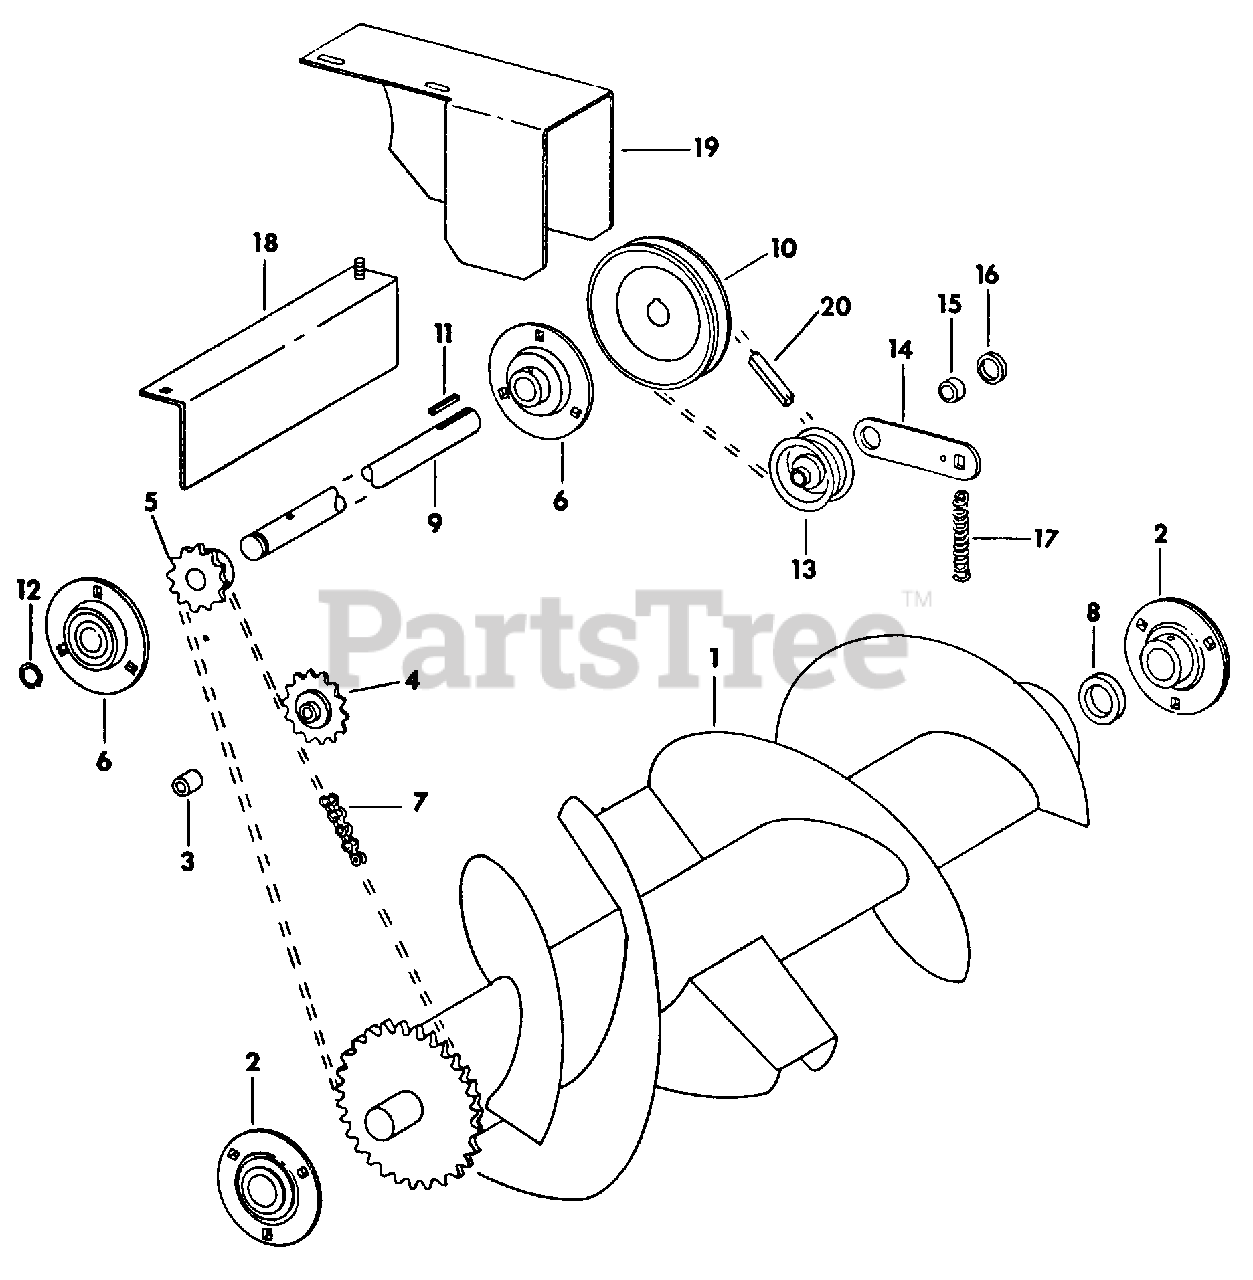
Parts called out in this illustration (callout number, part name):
1	Rotor Assy, Welded
2	Bearing w/o Locking Collar
3	Spacer, Chain Idler Mounting
4	Idler, Chain
6	Bearing w/Set Screw
7	Chain, Roller
8	Spacer, Rotor
9	Shaft, Drive
11	Key, 3/16 X 1 Sq-Parallel
12	Ring, Shaft Retaining
13	Pulley, Idler
14	Arm, Idler
15	Bushing, Idler Arm Pivot
16	Spacer, Idler Arm Pivot
17	Spring, Idler Arm Tension
18	Shield, Shaft
19	Guard, Belt
20	Belt, Drive
